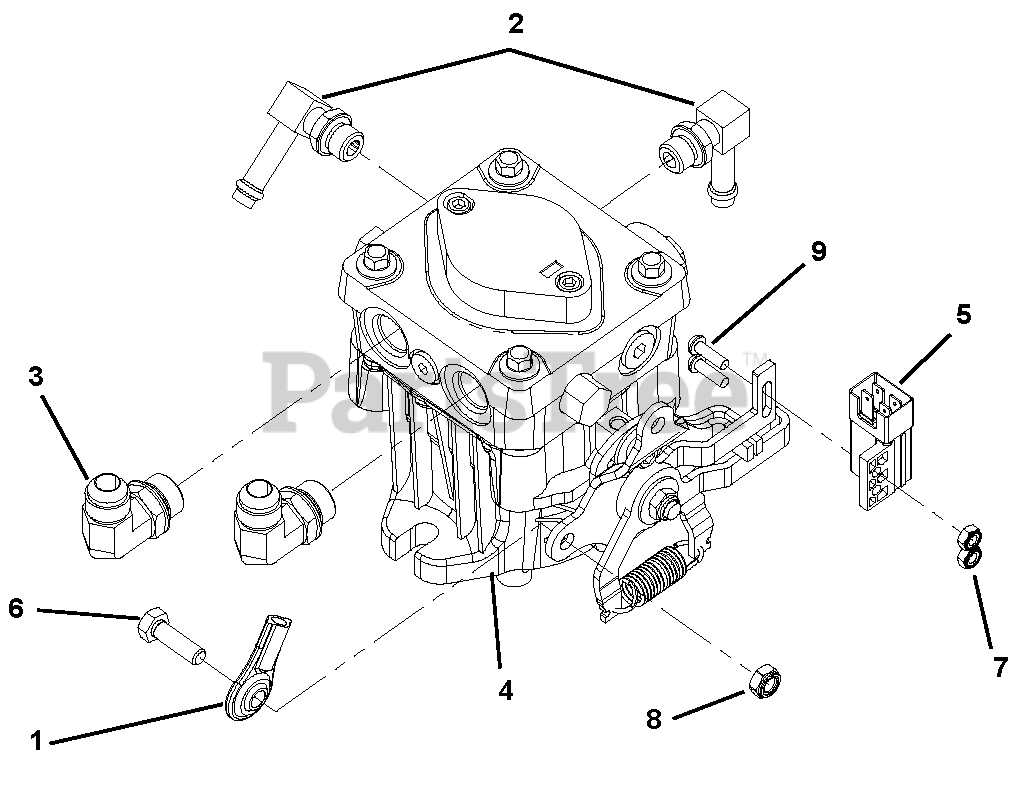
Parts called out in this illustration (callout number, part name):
1	Alignaball, 5/16 RH/Thread
2	Fitting, 90 9/16MOR x 3/8 Hose
3	Fitting
4	Pump, Hydraulic LH
5	Switch, Plunger Diametral Pitch -N.O. -N.C.
6	Bolt, Hex 5/16-18 x 1.00 Grade 5
7	Nut, Locking, Nylon 10-24 w/Insert
8	Nut, Locking, Nylon .312-18
9	Screw, Machine 10-24 x .62 P/HD
NS	Pump Seal Kit
